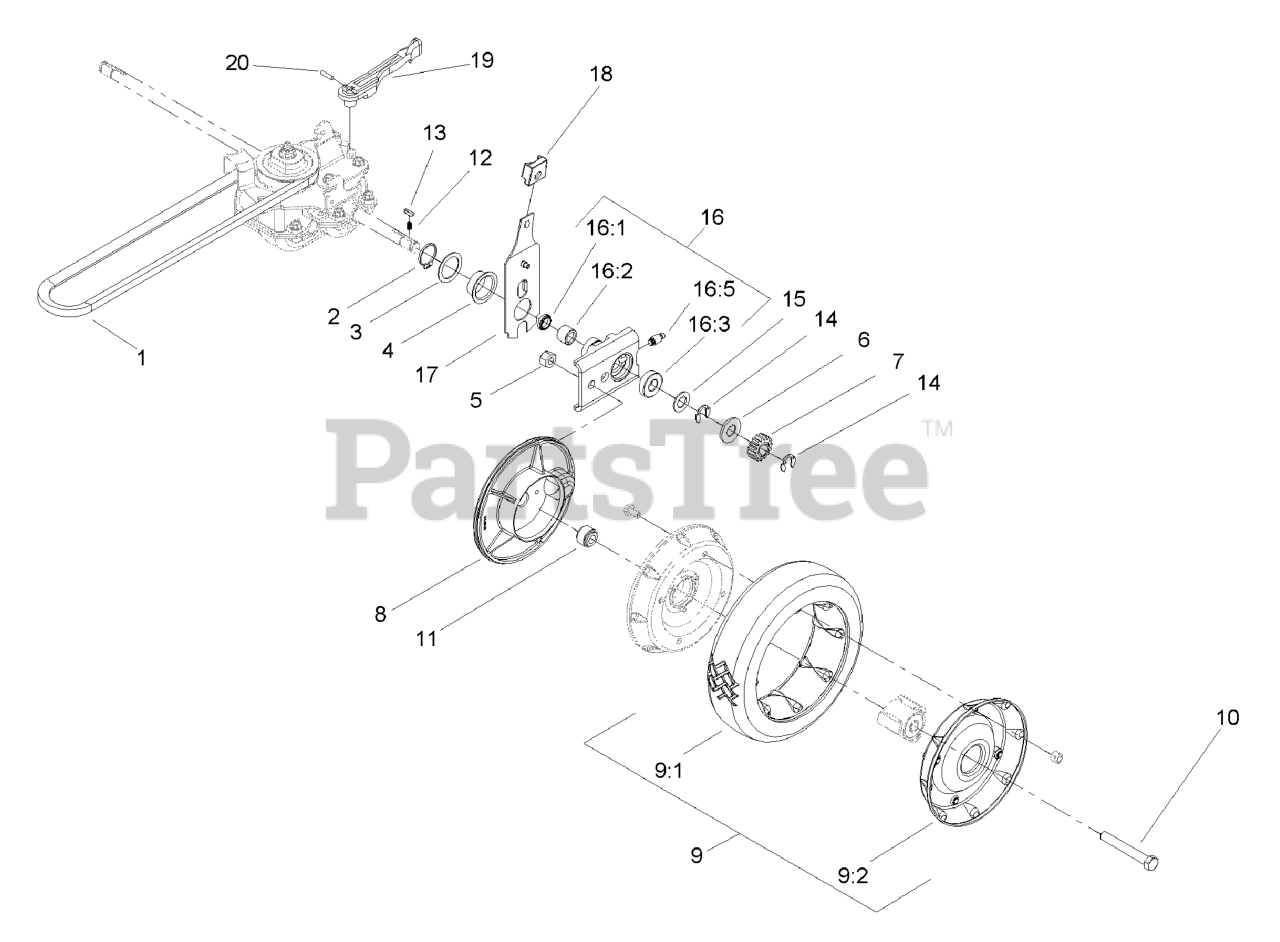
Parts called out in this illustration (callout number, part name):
1	V-BELT
2	RING-RETAINING
4	CAP-END
5	NUT-LOCK, CONE
6	WASHER-THRUST, OUTER
7	GEAR-PINION
8	COVER-WHEEL
9:2	Wheel Asm
10	SCREW-HH
11	SPACER-COVER, WHEEL
12	SPRING-COMPRESSION
14	RING-RETAINING
15	WASHER-THRUST, OUTER
16	PIVOT ARM ASM
16:1	SEAL-OIL
16:3	BEARING-WHEEL
17	REAR SPRING ARM ASM
18	KNOB-ARM
19	LEVER-SHIFT
20	PIN-SPRING
